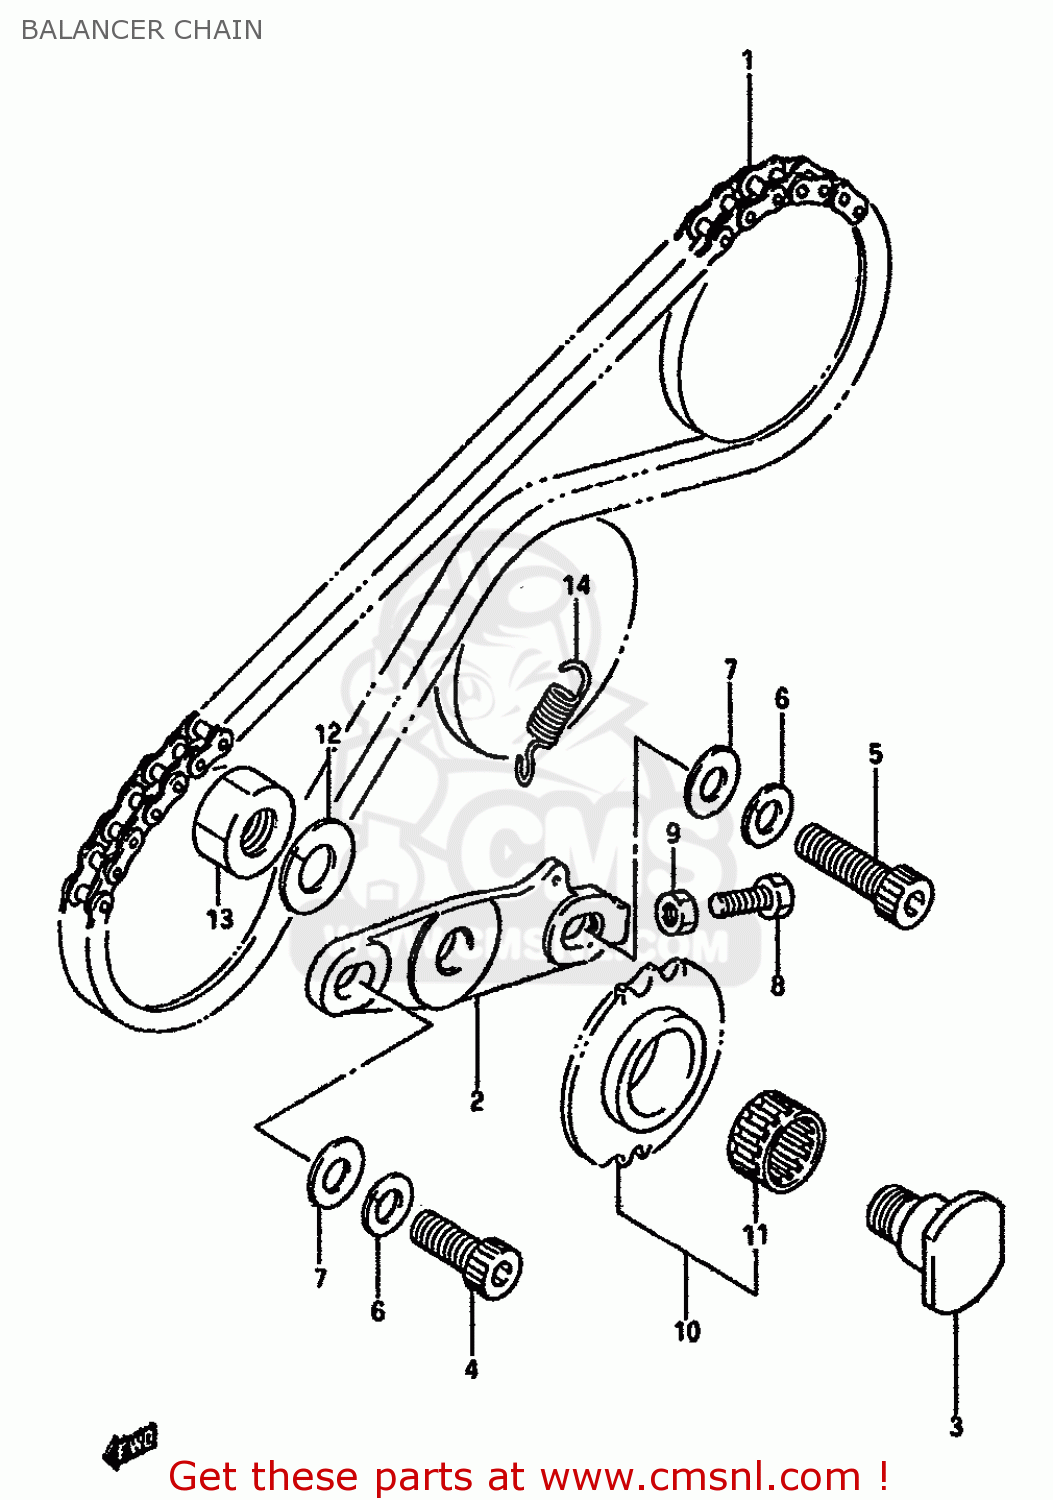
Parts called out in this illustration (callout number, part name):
1	CHAIN,BALANCER
2	BRACKET,BALANCER CHAIN
3	SHAFT,BALANCER CHAIN TENSIONER
4	BOLT(8X22)
5	BOLT, REAR (8X30)
6	LOCK WASHER
7	WASHER
8	BOLT 5X20
9	NUT
10	SPROCKET,BALANCER CHAIN
11	BEARING(17X23X12)
12	WASHER,LOCK 12
13	NUT
14	SPRING
